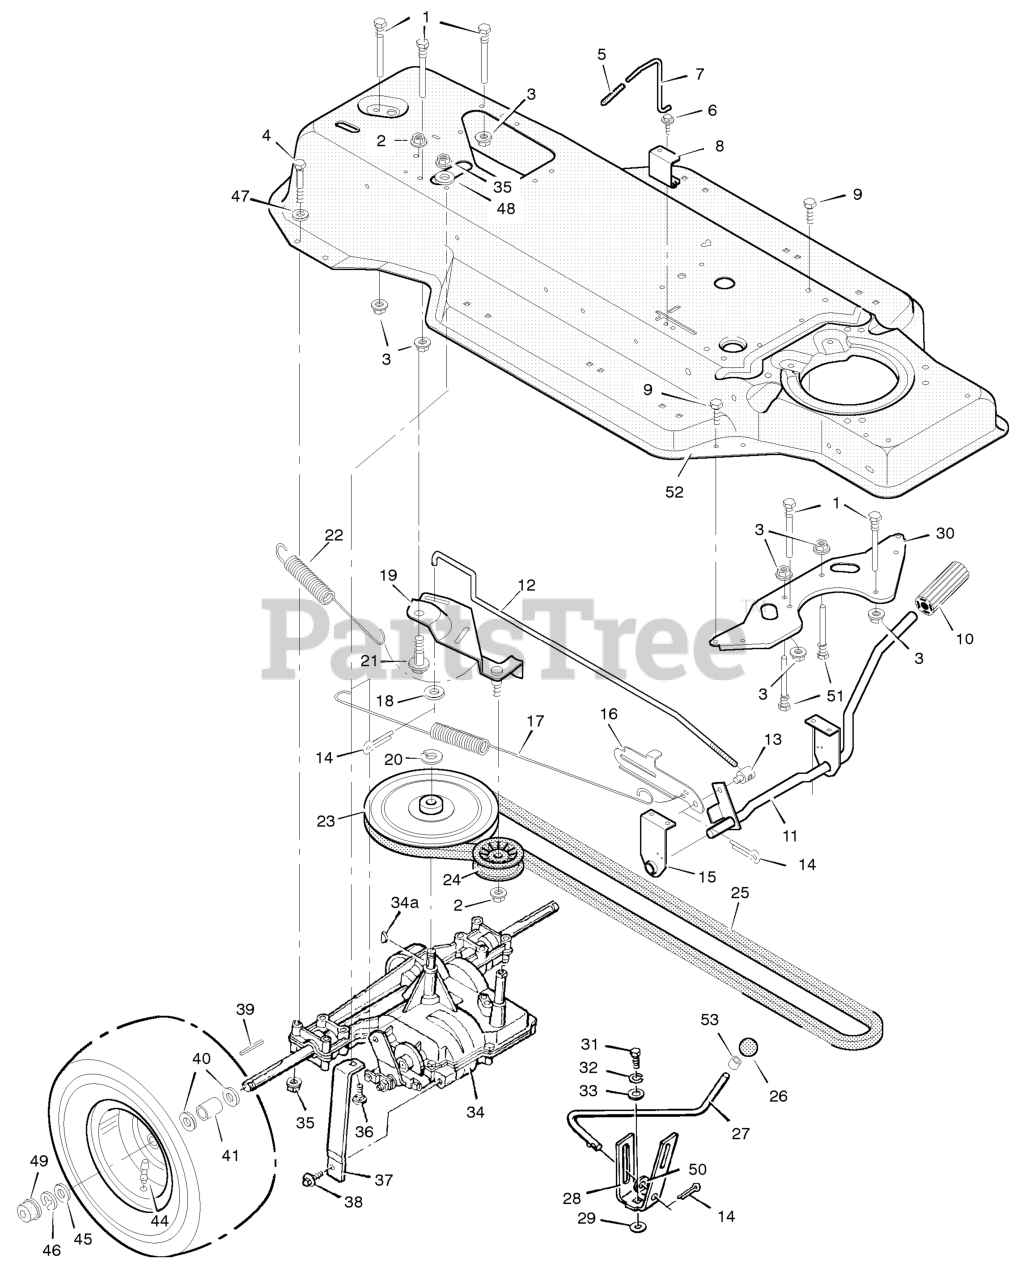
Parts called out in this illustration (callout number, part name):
1	Guide, Belt
2	Locknut, Flange
3	Nut, Flange
4	Bolt, Hex
7	Rod, Control
8	Guide, Bracket
10	Clutch and Brake Pedal
11	Lever Assembly
12	Rod, Clutch
13	Nut, Adjustable
14	Pin, Cotter
15	Bracket, Support
16	Latch, Park Brake
17	Spring, Brake Extension
18	Washer
19	Bracket Assembly, Idler
20	Ring, Retainer
21	Bolt, Shoulder
22	Spring, Drive Extension
23	Pulley, Motion Drive
24	Pulley, Backside Idler
25	Belt, Motion Drive
26	Knob, Shift Lever
27	Lever, Shift
28	Yoke, Shift
30	Plate, Belt Guide
31	Bolt, Hex
32	Lockwasher
34	Transaxle, Peerless **
34A	Woodruff Key No. 9
35	Nut, Flange
36	Bolt, Carriage
37	Support, Transaxle
39	Key, Square
41	Spacer, Transaxle
43	Wheel & Tire Assembly
44	Stem, Valve
47	Washer
49	Hub Cap
50	Washer
51	Guide, Belt
52	Frame Assembly
53	Ring, Tolerance
57	Screw
